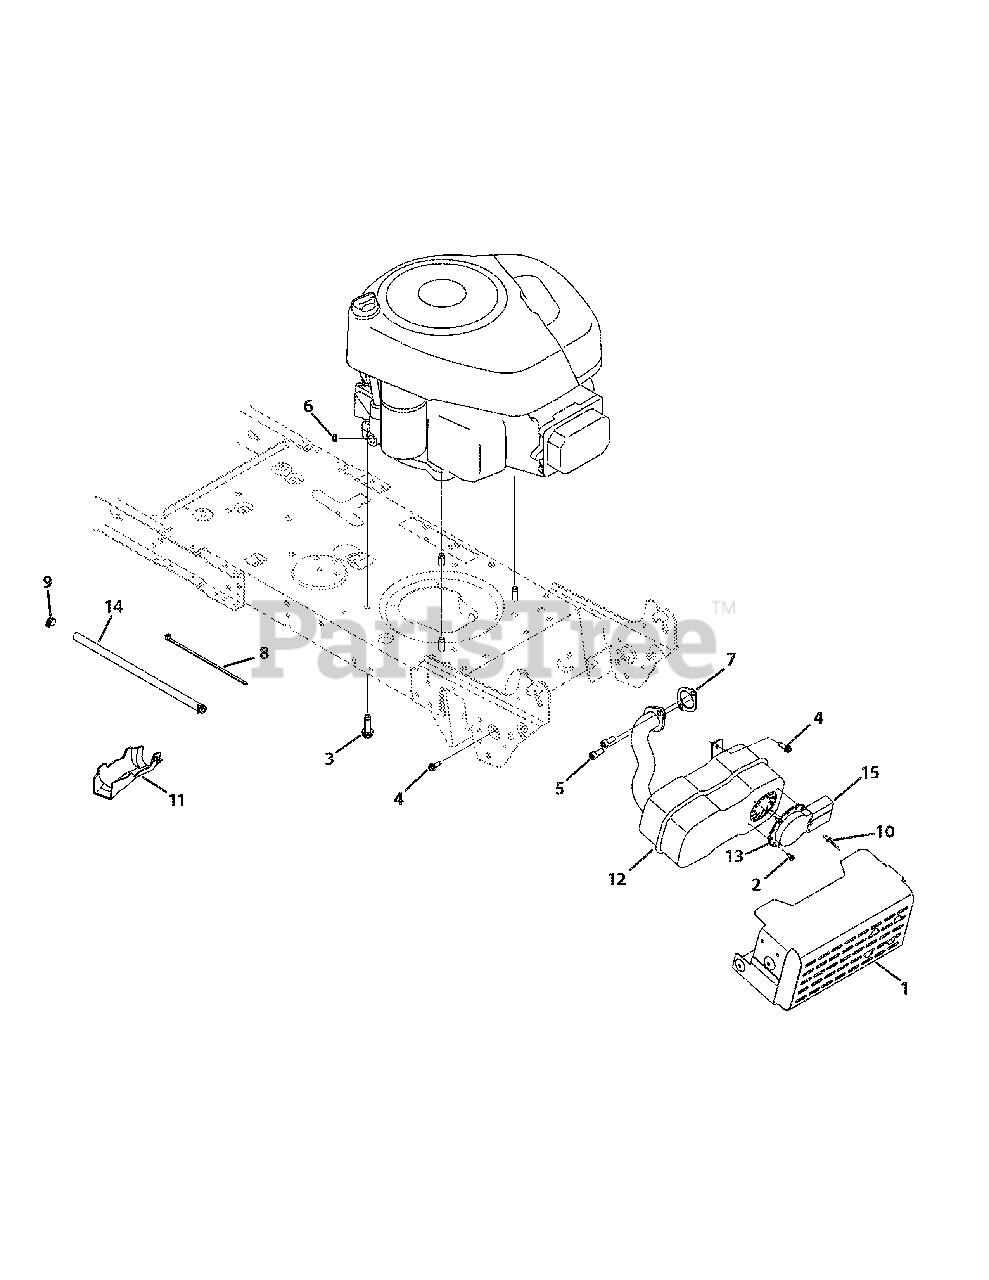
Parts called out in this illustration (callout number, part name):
1	Muffler Shield
2	Hex Wash HD AB S-Tapp Scr #8-.50
3	Hex Wash S-Tapp Scr 3/8-16 x 1.0
4	Thd Forming Scr. 1/4-20 x .75 Lg.
5	Socket HD Cap Scr. 5/16-18 x .75
6	Sems Nut 1/4-20
7	Exhaust Gasket (B&S)
8	Cable Tie
9	Hose Clamp
10	Rivot, Pop, .188 x .3
11	Oil Drain Sleeve
12	Muffler, Single Inlet
13	Muffler Deflector
14	Fuel Hose; Low Permeation
15	Muffler Deflector
